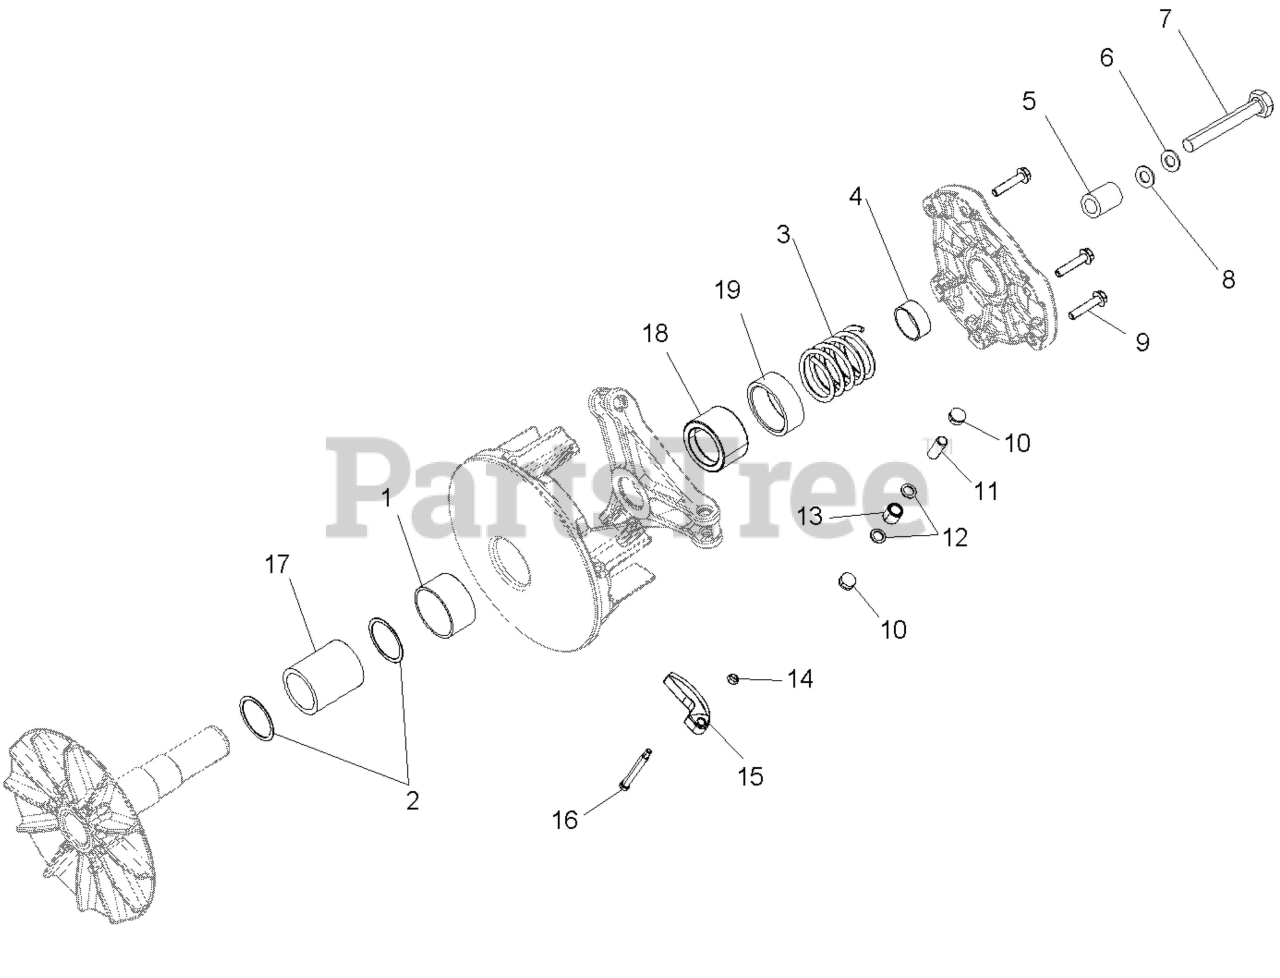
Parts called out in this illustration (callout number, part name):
1	BEARING-DU,1.75ID
2	WASHER-CLUTCH,VESPEL
3	SPRING-CLUTCH, 35-240
4	BEARING COVER, .75IN
6	WASHER LOCK
7	BOLT-CLUTCH ATV,7/16X20X8
8	WASHER(10) *
9	SCR-1/4-20X1.25 HX/FL GR5
10	BUTTON,CLUTCH,RUBBER BACKED
11	PIN-ROLLER,(10)
12	WASHER-CLUTCH,SPIDER ROLLER
12	WASHER
13	ROLLER/BUSHING ASM.(3) **
14	NUT FLEXLOC(10)
15	WEIGHT-SHIFT,25-52G,PM
16	BOLT,SHOULDER(10)
17	BEARING-NEEDLE
18	SPACER-CLUTCH
19	SPACER-CLUTCH,LIMITER
